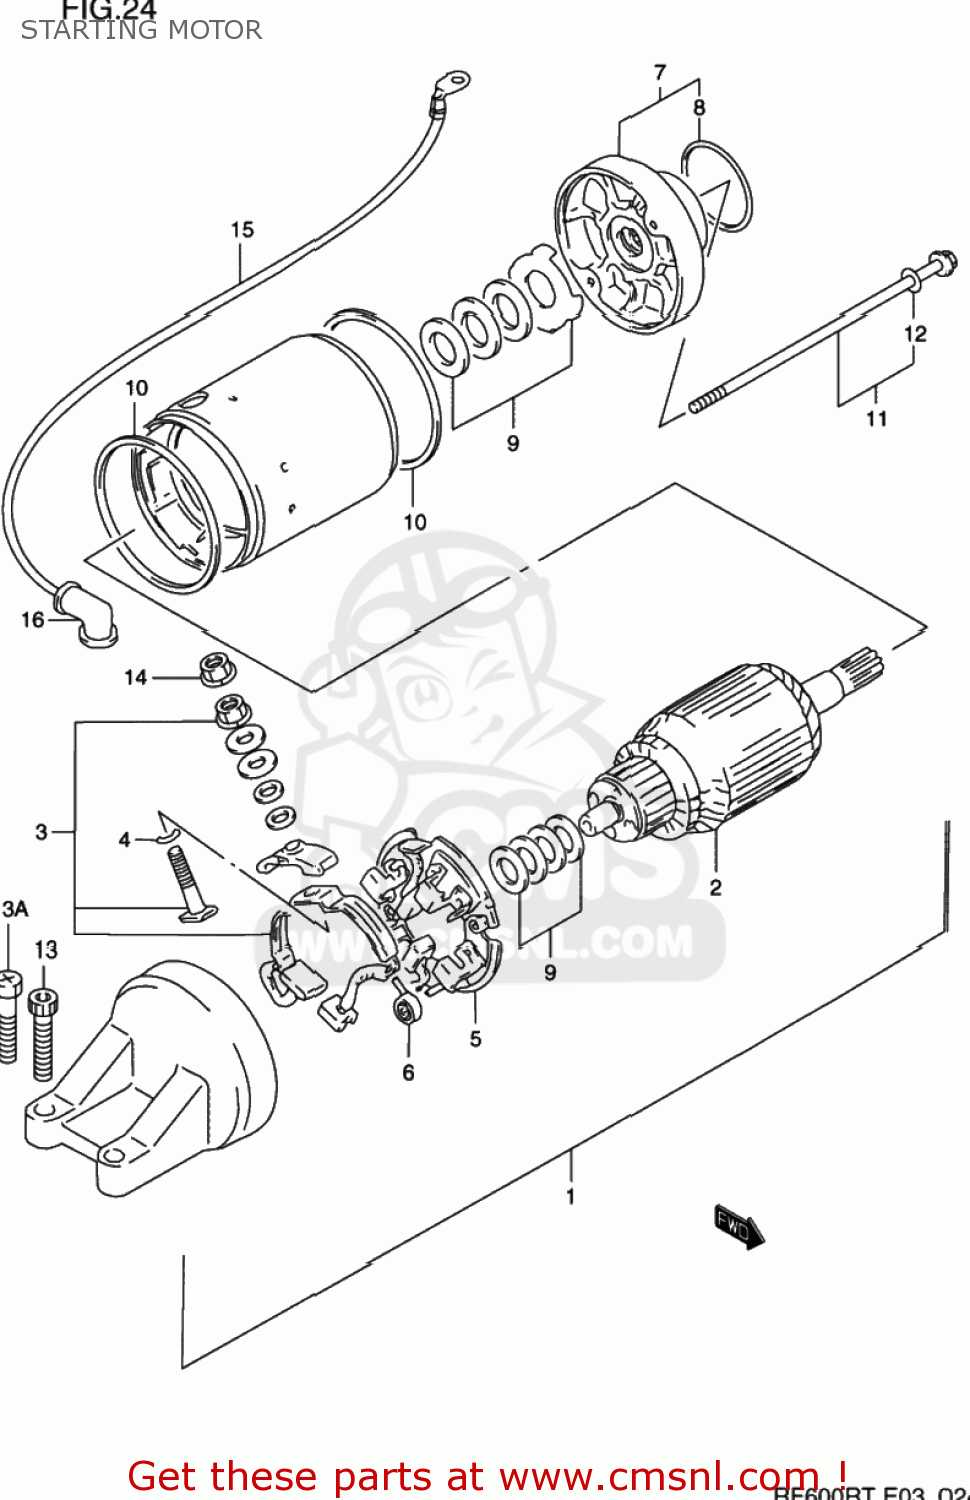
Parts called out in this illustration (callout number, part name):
1	MOTOR ASSEMBLY,STARTING
2	ARMATURE
3	TERMINAL SET,BRUSH,PLUS
4	O RING
5	BRUSH,HOLDER SET
6	SPRING,BRUSH
7	BRACKET ASSEMBLY,FRONT
8	O-RING
9	SHIM SET,STARTING MOTOR
10	O RING
11	BOLT SET,STARTING MOTOR
12	O RING
13	BOLT,OIL PAN
13A	SCREW (6X25)
14	NUT
15	WIRE,STARTER MOTOR LEAD
16	CAP,STARTER MOTOR LEAD
